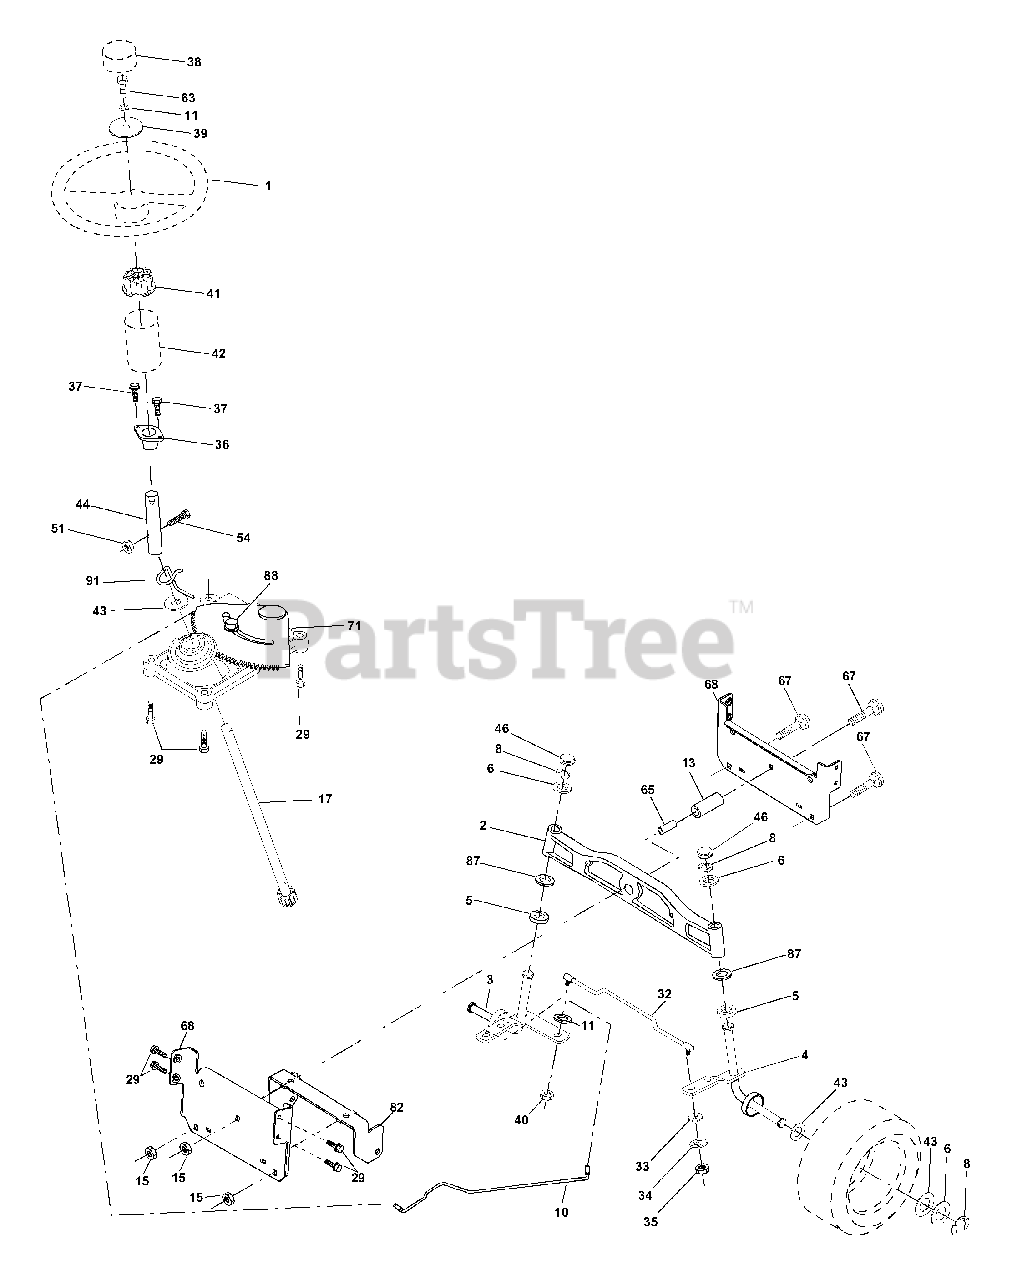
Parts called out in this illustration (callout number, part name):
1	Wheel Steering
2	Axle Cast Lt Machined
3	Spindle Asm LH
4	Spindle Asm RH
5	Bearing Race Thrust Harden
6	Washer 25/32 X 1-5/8 X 16 Ga
8	Ring Klip #t5304-75
11	Washer Lock Hvy Hlcl Spr 3/8
13	Spacer Brg Axle Front
15	Nut Hex Flange Lock
17	Shaft Asm Strg
29	Screw 3/8-16x3/4
32	Rod Tie Ball J
33	Washer 11/32 x 3/4 x 16 Ga.
34	Washer Lock Hvy Helical 5/16
35	Nut Crown Lock 5/16-24Unf
36	Bushing Strg
38	Insert Cap Strg Wh
39	Washer 13/32 x 1-1/20 x 11 Ga
40	Lock nut
41	Adaptor Wheel Strg
42	Boot Steering Shaft
43	Washer 25/32 X 1 1/4 X 16 Ga
44	Extension Steering Shaft LR/LT
46	Cap Spindle Fr Top Blk
51	Nut Lock Hex w/Ins 5/16-18
54	Bolt Fin Hex 5/16-18 Unc x 1-1/4
63	Bolt Fin Hex 3/8-16unc x 1 Gr. 5
65	Spacer Brace Axle
67	Bolt Rdhd Sq 3/8-16 x 2-1/4
68	Axle, Brace
71	Steering Asm
82	Bracket Susp Chassis Front
87	Washer Flat .781 x 1-1/2 x .14
88	Bolt Shoulder 7/16-20
91	Clip Steering
